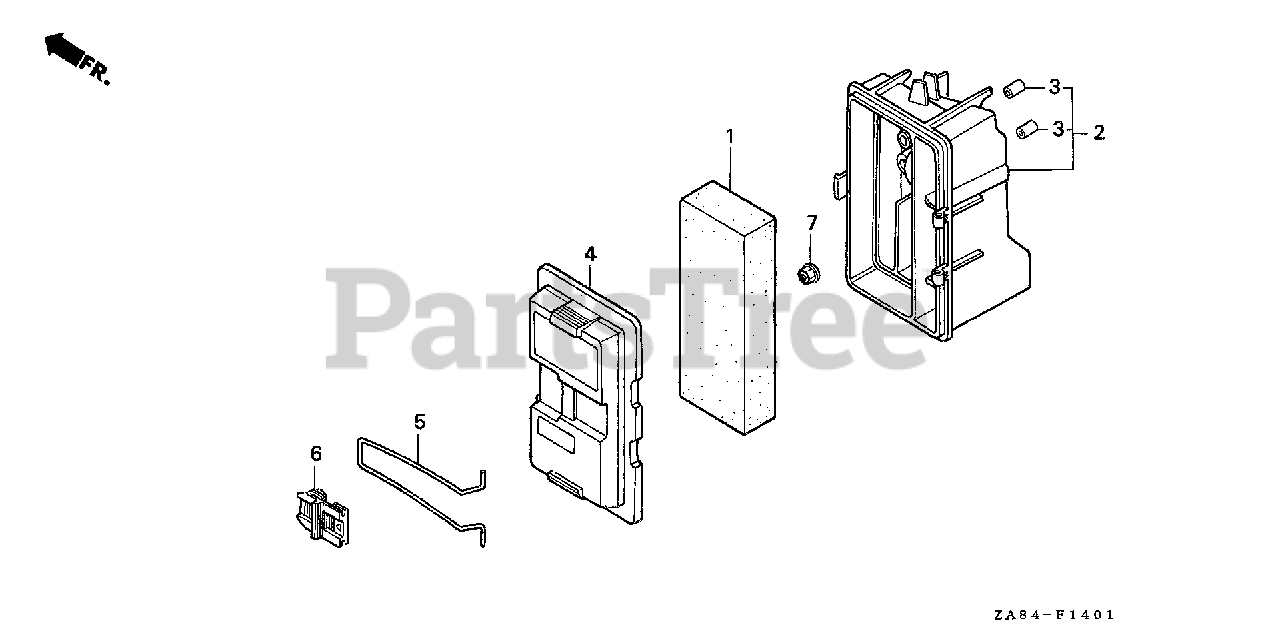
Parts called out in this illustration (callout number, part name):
1	ELEMENT, AIR CLEANER
2	CASE SET, AIR CLEANER
2	HOUSING, AIR CLEANER
3	COLLAR, AIR CLEANER
4	COVER, AIR CLEANER
5	SPRING, SETTING
6	KNOB, SETTING
7	NUT, FLANGE (6MM)
